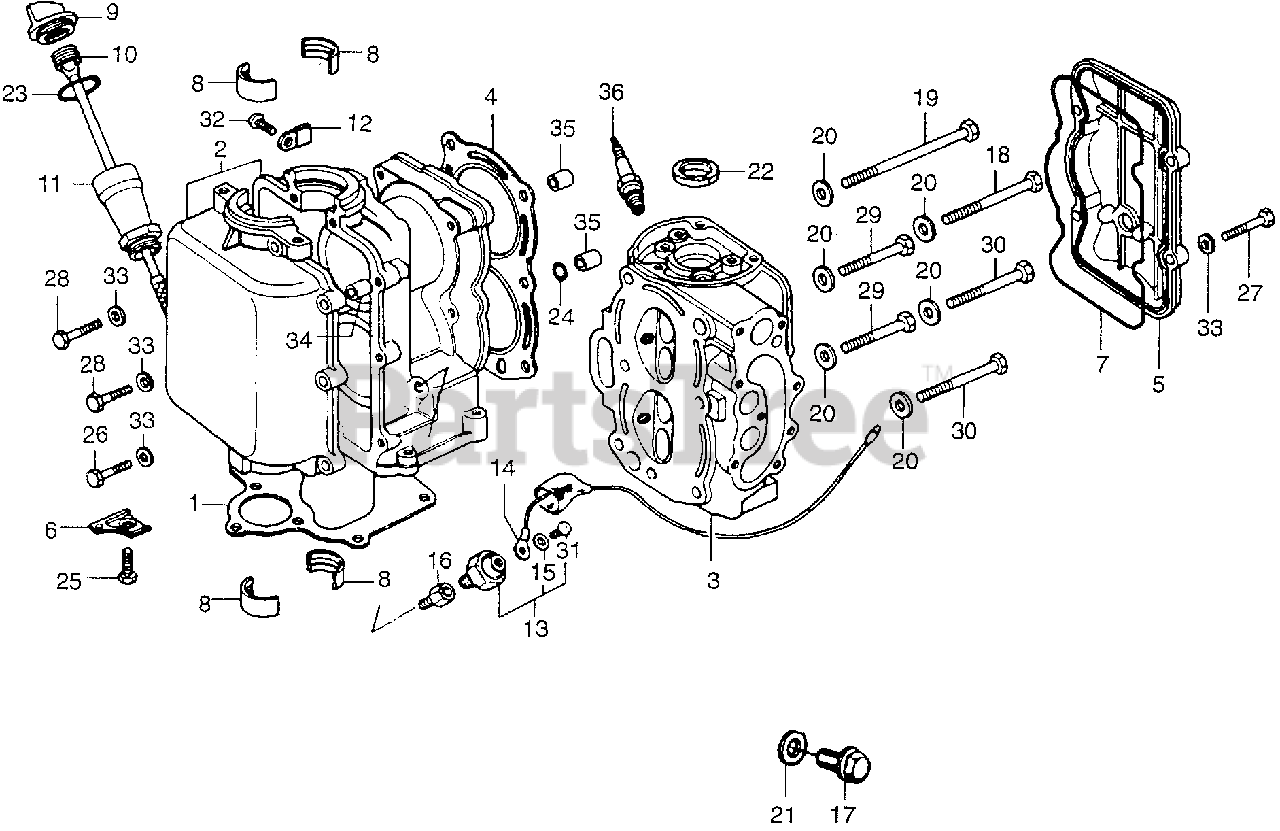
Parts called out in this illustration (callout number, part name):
1	GASKET, OIL PAN
3	CYLINDER HEAD
4	GASKET, CYLINDER HEAD
5	COVER, CYLINDER HEAD
6	PLATE, BREATHER
7	GASKET, CYLINDER COVER (NOT AVAILABLE)
8	BEARING, CRANKSHAFT (STD) (NOT AVAILABLE)
9	CAP, OIL
10	DIPSTICK, OIL
11	JOINT, OIL FILLER (NOT AVAILABLE)
17	BOLT, OIL CHECK (NOT AVAILABLE)
18	BOLT, HEAD (8X70)
19	BOLT, HEAD (8X94)
20	WASHER, HEAD (8MM)
21	WASHER, SEALING
22	OIL SEAL (16X28X6)
23	O-RING (26X2.7)
24	O-RING (9.8X2.2) (NOT AVAILABLE)
25	BOLT, HEX. (6X10) (NOT AVAILABLE)
26	BOLT, HEX. (6X25)
27	BOLT, HEX. (6X28)
28	BOLT, HEX. (6X35) (NOT AVAILABLE)
29	BOLT, HEX. (8X50) (NOT AVAILABLE)
30	BOLT, HEX. (8X65) (NOT AVAILABLE)
32	SCREW, PAN (5X8)
33	WASHER, PLAIN (6MM)
34	PIN A, DOWEL (8X14)
35	PIN A, DOWEL (10X14)
36	SPARK PLUG (D5HS) (NGK)
